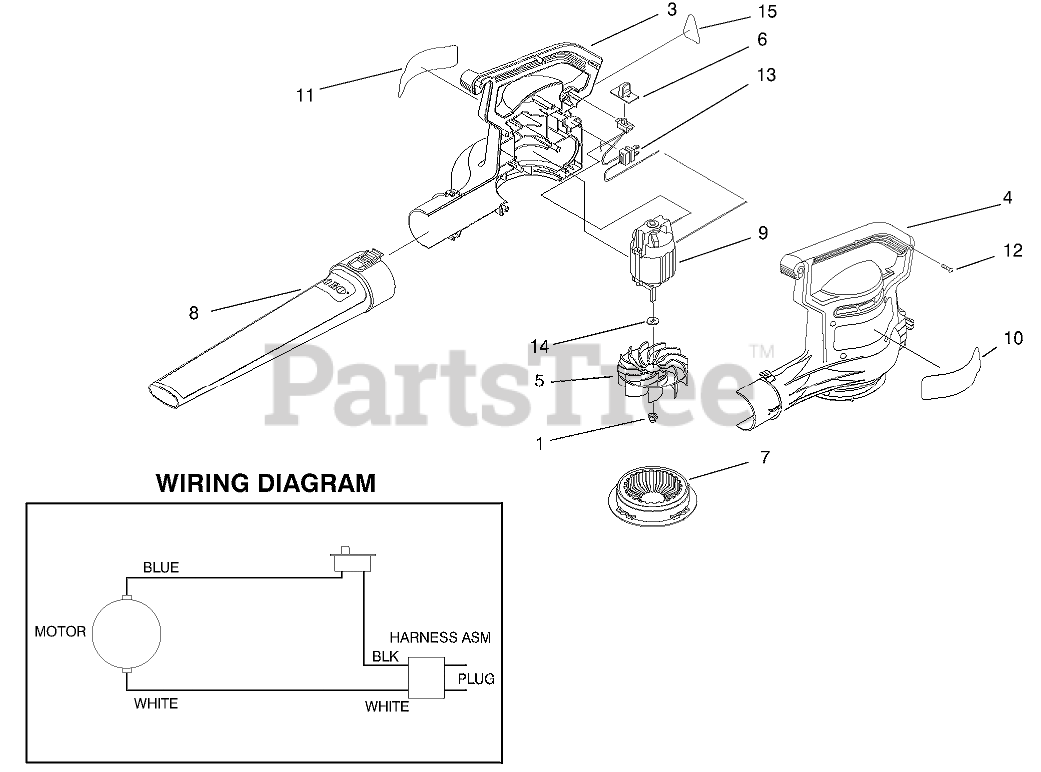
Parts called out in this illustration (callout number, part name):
1	NUT-LOCK, NI
3	Housing-RH
4	HOUSING-LH
5	IMPELLER, BLOWER
6	COVER-SWITCH
7	COVER - INLET
8	TUBE - BLOWER SHORT
10	DECAL - POWER SWEEP
11	DECAL - WARNING
12	SCREW-PPH
13	HARNESS ASM
14	WASHER
15	DECAL - INFORMATION
